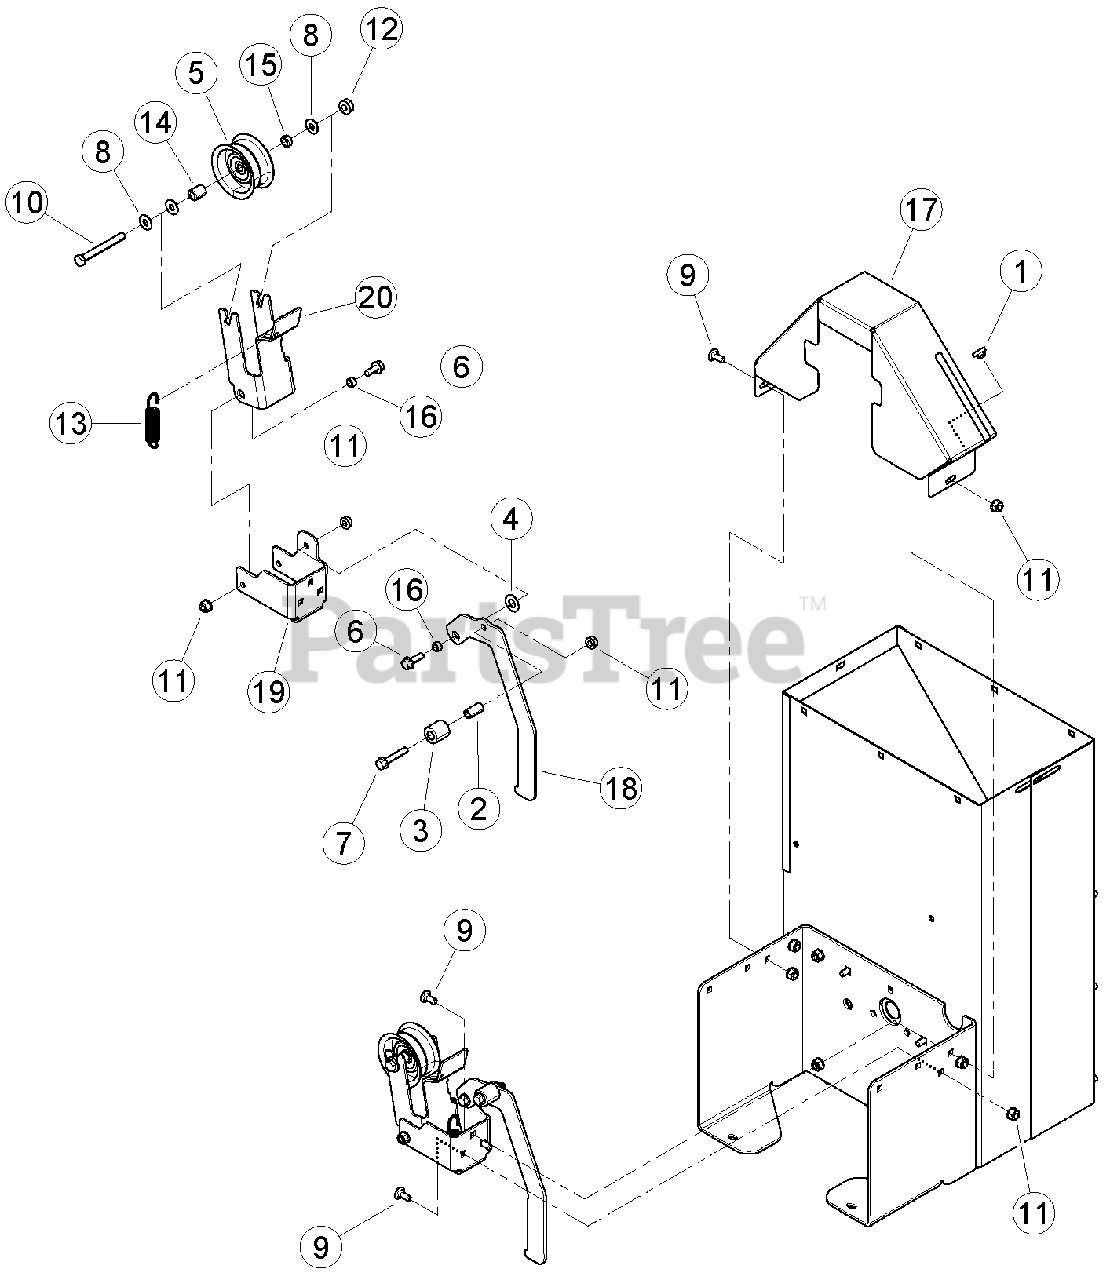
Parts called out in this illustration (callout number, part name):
1	BUMPER, RUBBER
2	SPACER, 0.5 X 1.00
3	ROLLER, 0.5 X 1.00 X 1.00 NYLON
4	WASHER, 1/2 INCH NYLON
5	IDLER, 2.75 X 1.25
6	BOLT, 5/16 X 7/8 FLANGE NC
7	BOLT, 5/16 X 1-3/4 FLANGE NC
8	WASHER, 5/16 FLAT ZP
9	BOLT, 5/16 X 3/4 CRG GR5 NC ZP
10	BOLT, 3/8 X 3-1/4 HEX GR5 ZP
11	NUT, 5/16-18 NYLOCK-FLANGE
12	NUT, 3/8-16 NYLOCK FLANGE
13	SPRING, 3/4"OD EXTENSION
14	SPACER, 3/4" LONG IDLER TUBE
15	SPACER, IDLER PIVOT
16	SPACER, .50 X .25
17	SHIELD, UPPER
18	HANDLE, ENGAGEMENT
19	MOUNT, IDLER BRACKET
20	BRACKET, IDLER 3 IN CHIPPER
